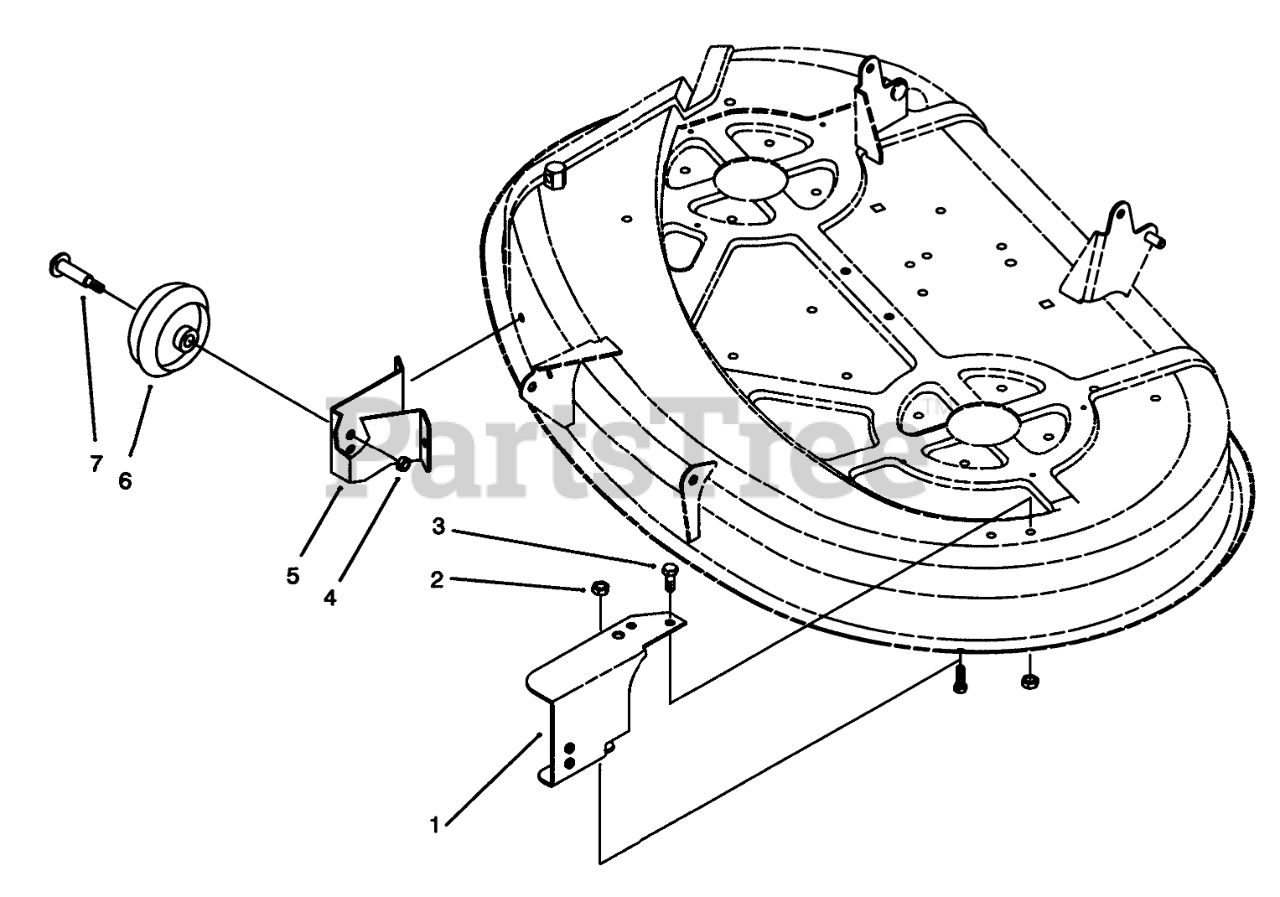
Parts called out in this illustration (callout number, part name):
1	LH WHEEL DECK BRKT
2	NUT-LOCK, NI
3	SCREW-HH
4	NUT-LOCK, NI
5	Bracket-R.H.
6	WHEEL-GAGE
7	SCREW-SHOULDER, HWH
